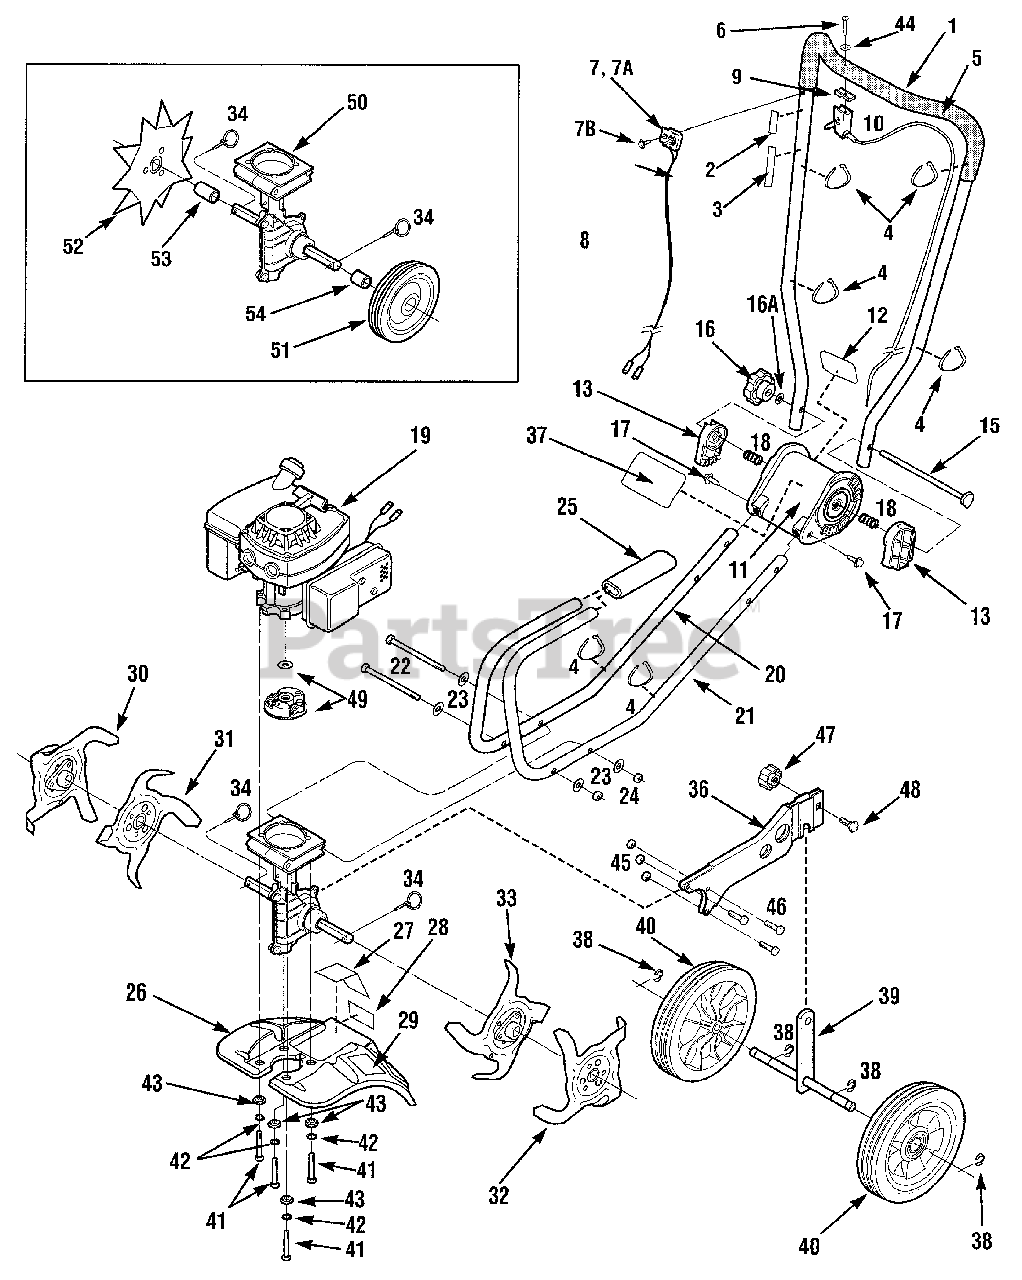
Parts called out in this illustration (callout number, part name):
1	Upper Handlebar Assy
2	Decal, On/Off Ignition Switch
3	Decal, Starting Stabilization
4	Tie, Plastic
5	Handlebar Grip, PVC
6	Screw, #10-16 x 1-1/2"
7	Switch, Engine Ignition
7A	Bracket Switch
7B	Screw, Phillips Hd., #12-24
8	Wire, Engine Ignition On/Off
9	Spacer, Throttle Control
10	Lever and Cable Assy, Throttle
11	Handlebar Pivot Assy.
12	Decal, Control Lever
13	Ratchet, Handlebar Pivot
15	Bolt, Handlebar Pivot
16	Knurled Knob, Handlebar Pivot
16A	Washer, Flat, 5/16"
17	Screw, Slotted Hex Hd., 1/4"-14 x 3/4"
18	Spring, Handlebar Pivot
19	Engine, 2HP Tecumseh
20	Lower Handlebar, Right Side
21	Lower Handlebar, Left Side
22	Bolt, Hex Hd., 1/4"-20 x 5"
23	Flat Washer, 1/4" I.D.
24	Locknut, 1/4"-20
25	Foam Sleeve, Lower Handlebar
26	Hood Assy.
27	Decal, Warning
28	Decal, Warning
29	Decal, Hot Surface Warning
30	Tine, Outer, Right-Hand Side
31	Tine, Inner, Right-Hand Side
32	Tine, Outer, Left-Hand Side
33	Tine, Inner, Left-Hand Side
34	Ring Lock Pin
34	Flat Washer
36	Wheel Bracket
37	Logo Decal
38	E-Rings
40	Wheel
41	Screw, Hex Cap, 1/4"-20 x 2"
42	Washer, Lock 1/4"-20
43	Spacer, Engine Mounting
44	Washer, Flat
45	Locknut, 1/4"-20
46	Screw, 1/4"-20 x 1"
48	Carriage Bolt
49	Clutch Rotor with Washer
50	Transmission Assembly
51	Edger Wheel
52	Edger Tine
53	Long Bushing
54	Short Bushing
